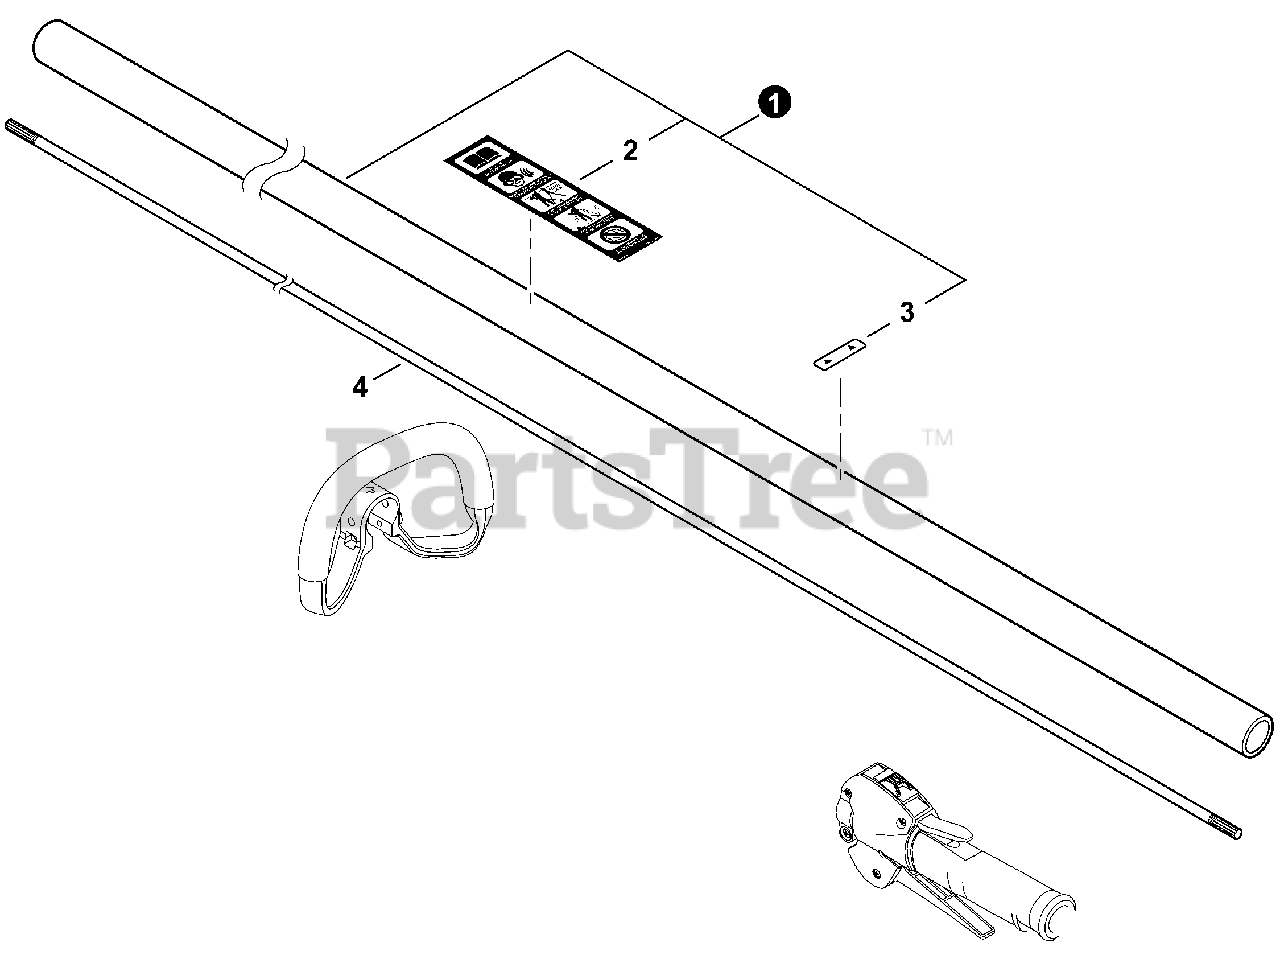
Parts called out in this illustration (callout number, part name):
1	MAIN PIPE ASSY
2	LABEL, CAUTION
3	LABEL - ALIGNMENT
4	DRIVESHAFT
